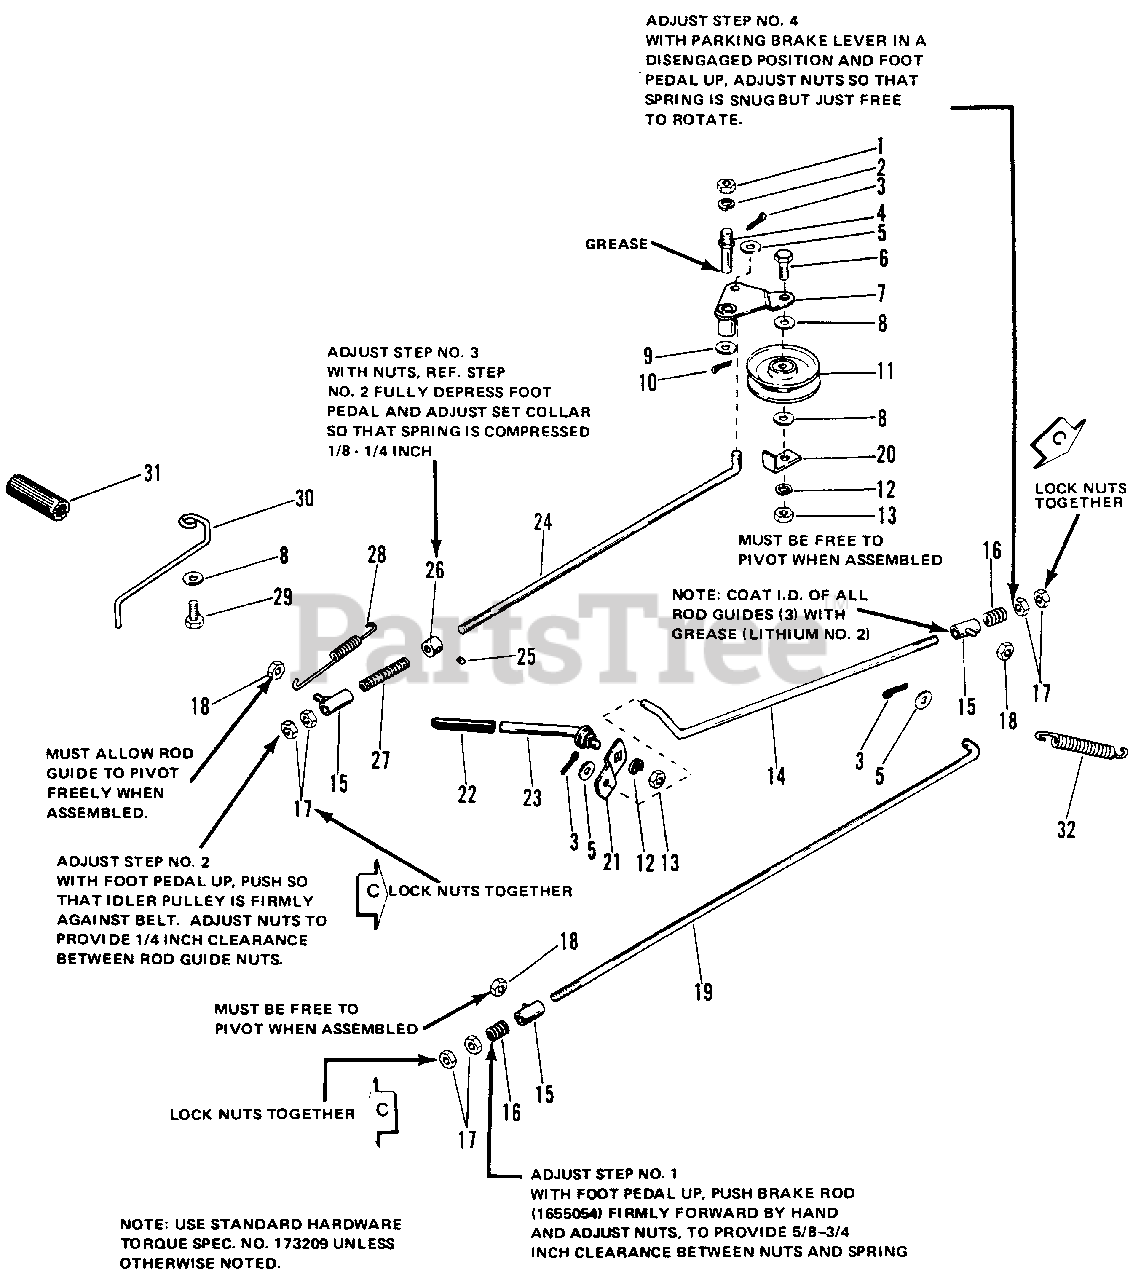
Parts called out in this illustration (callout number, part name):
1	NUT, Hex, full, 7/16-14
2	LOCKWASHER, 7/16
3	PIN, Cotter, 3/32 x 3/4
5	WASHER, Plain, 1/4
6	CAPSCREW, Hex, 3/8-16 x 1-1/2
7	IDLER ASSEMBLY
8	WASHER, Plain, 5/16
9	WASHER, Plain, 3/8
10	PIN, Cotter, 1/8 x 3/4
11	PULLEY, Idler
12	LOCKWASHER, 3/8
13	NUT, Hex, 3/8-16
14	ROD, Parking Brake
15	ROD GUIDE ASSEMBLY
17	NUT, Hex, full, 5/16-18
18	LOCKNUT, Hex, 5/16-18
19	ROD, Brake
20	GUIDE, Belt
21	ARM, Pivot
22	GRIP
23	HANDLE, Control
24	ROD, Clutch
25	SETSCREW, 1/4-20 x 3/8 Sq. Hd.
26	COLLAR, Set
28	SPRING, Return
29	SCREW, Taptite, 5/16-18 x 7/8
30	STOP, Belt
31	PEDAL, Brake
32	SPRING, Tension
